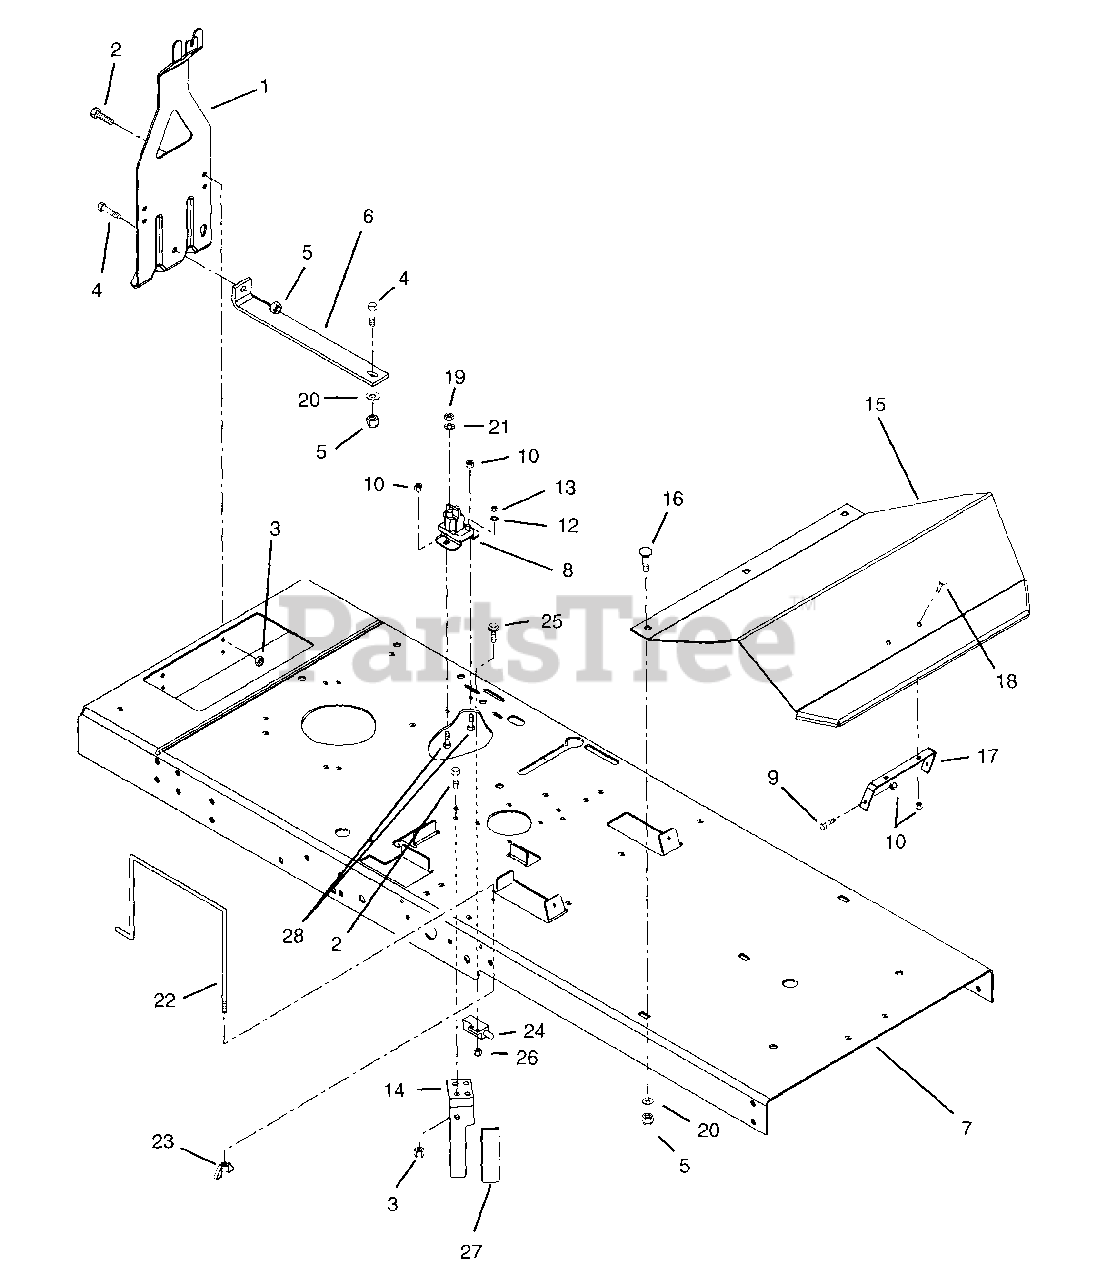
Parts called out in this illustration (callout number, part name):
1	HITCH, TRAILER
2	@BLT-HEX .31-18X.75 GR5 YWZC
3	@NUT-LK-CTR .31-18 YWZC
4	@BLT-HEX .38-16X1.00 GR5 YWZC
5	@NUT-LK-CTR .38-16 YWZC
7	FRAME
8	SOLENOID
9	@BLT-HEX .25-20X.75 GR5 YWZC
10	@NUT-LK-CTR .25-20 YWZC
11	@BLT-HEX .38-16X2.00 GR5 YWZC
12	@WSHR-LK-EXT.200X.402X.022YWZC
13	NUT 10-32 YWZC
14	CLUTCH STOP
15	FOOTREST
16	@BLT-RDHDSQNK .38-16X.75 G2YWZ
17	BRACKET, FOOTREST
18	@BLT-RDHDSQNK .25-20X.50 G5YZ
19	NUT-JAM .31-24 YWZC
20	@WSHR-FL-STL.406X.812X.065 YWZ
21	WSHR-LOCK INT .31 YWZC
22	BATTERY ROD
23	NUT-LK WING .250-20 YWZC
24	SWITCH- SINGLE POLE N.O.
25	BLT-HEX FWH #10X.750 YWZC
26	@NUT-LK-NYL 10-24 W/INSRT YWZC
28	@BLT-HEX .25-20X.50 GR5 YWZC
